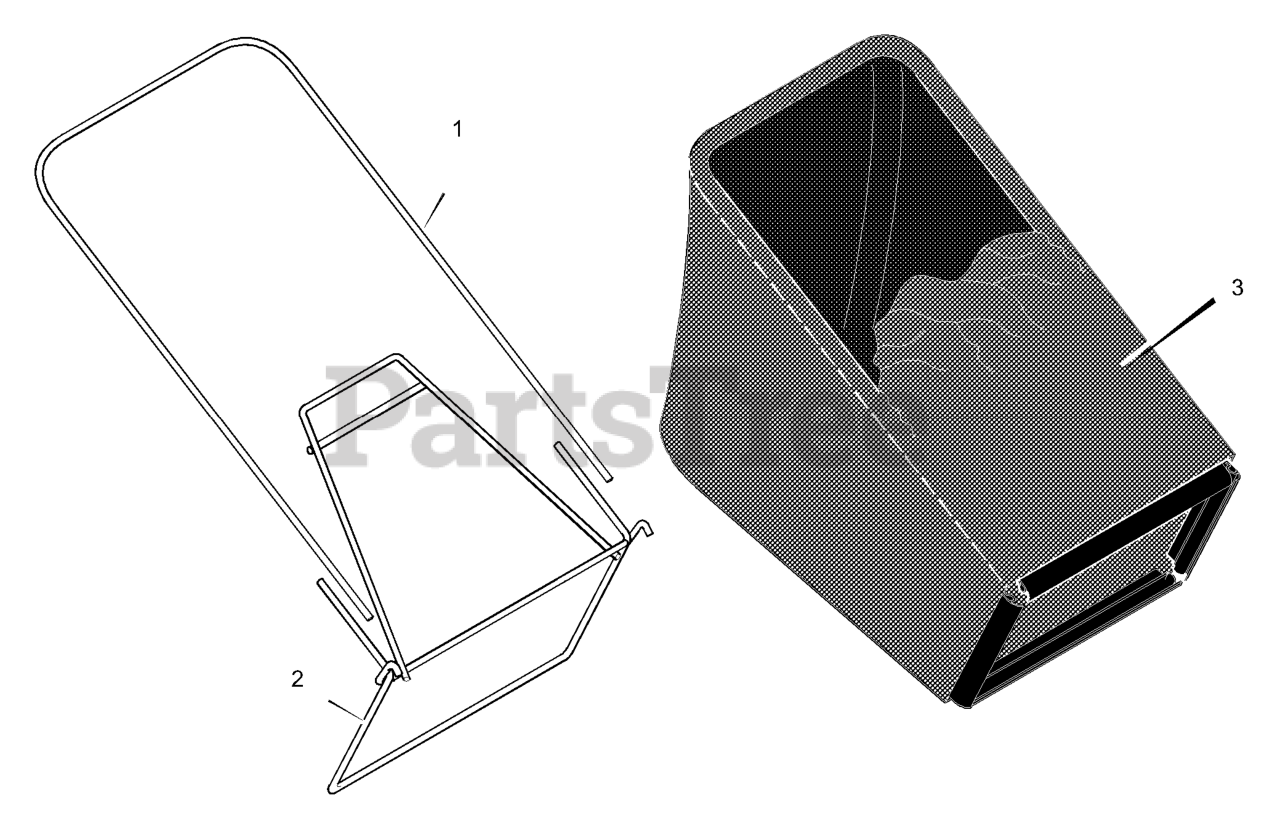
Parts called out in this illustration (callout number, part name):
1	Tube, Bag
2	Frame Assembly
3	Bag, Cloth - Black
